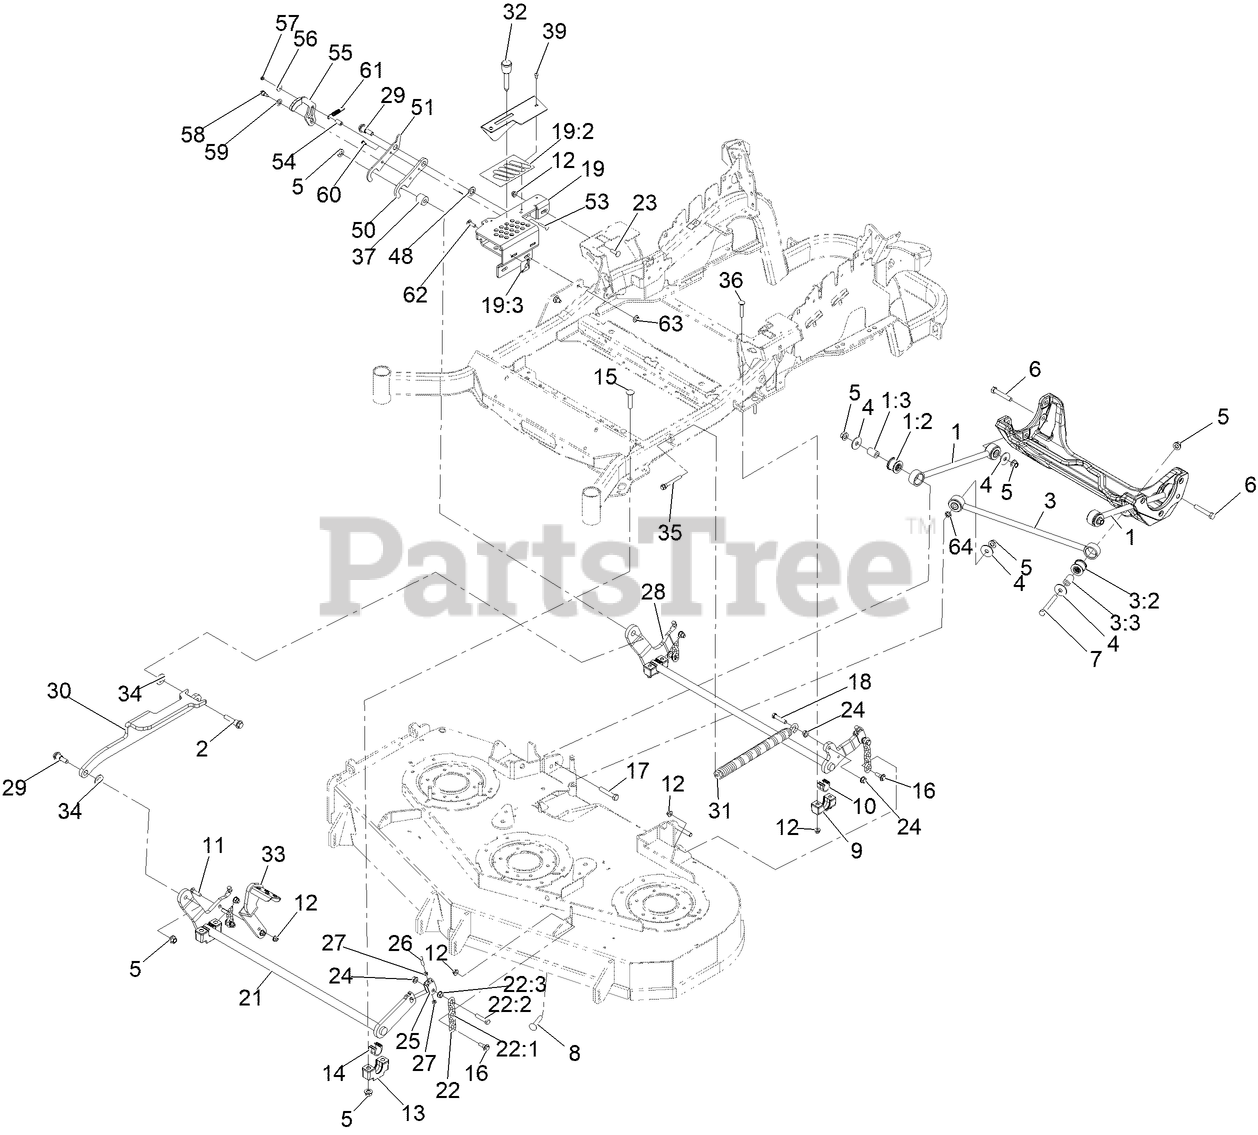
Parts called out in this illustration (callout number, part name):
1	DECK STRUT ASM
1:2	BUSHING-SUSPENSION, RUBBER
2	SCREW-HHF, SHOULDER
3	PANHARD ROD ASM
3:2	BUSHING-SUSPENSION, RUBBER
4	WASHER-THRUST
5	Nut-Lock 1/2-13
6	SCREW-HH
7	SCREW-HH
8	SCREW-CARR
9	SUPPORT-CROSS SHAFT, BEARING REAR
10	BEARING-CROSS SHAFT, REAR
11	SCREW-CARR
12	NUT-HF, NI
13	SUPPORT-CROSS SHAFT, BEARING
14	BEARING-CROSS SHAFT, FRON
15	Bolt-Carriage 1/2-13 X 2 1/2 Spl Neck
16	SCREW-SHOULDER, HHF
17	SCREW-HH
18	SCREW-HH
19	ASM-HOC Box W/ Decals
19:2	Decal-HOC
19:3	DECAL-PARK BRAKE, CE
21	Weld-Xshaft Front
22	DECK LIFT CHAIN ASM
22:1	CHAIN-LIFT, DECK
22:2	SCREW-HH
23	Bolt-Carriage 3/8-16 X 1 1/4
25	YOKE-ADJUST, DECK
26	SCREW-HH
27	NUT-JAM
28	Weld-Xshaft Rear
29	SCREW-SHOULDER, HHF 1/2-13 X 1.12
30	Link-Decklift
31	SPRING-EXTENSION
32	ASM- HOC PIN
33	LEVER-FOOT
34	WASHER-FLAT
35	BOLT-SHOULDER
36	Bolt-Carriage 3/8-16 X 2 1/4
37	Bushing- Link
39	SCREW-TPH THD FORM
50	Plate- Pawl
51	Plate- Pawl
53	SCREW-CARR
54	Spacer- 0.50" OD
55	Lever- Transport W/Grip
57	NUT-LOCK, NI
58	BOLT-SHOULDER
59	SPACER
60	SCREW-HWH
61	Spring- Extension
62	Bolt-Carriage 3/8-16 X 1 1/4
63	Nut-Nyloc 3/8-16 Flg
64	NUT-PUSH
